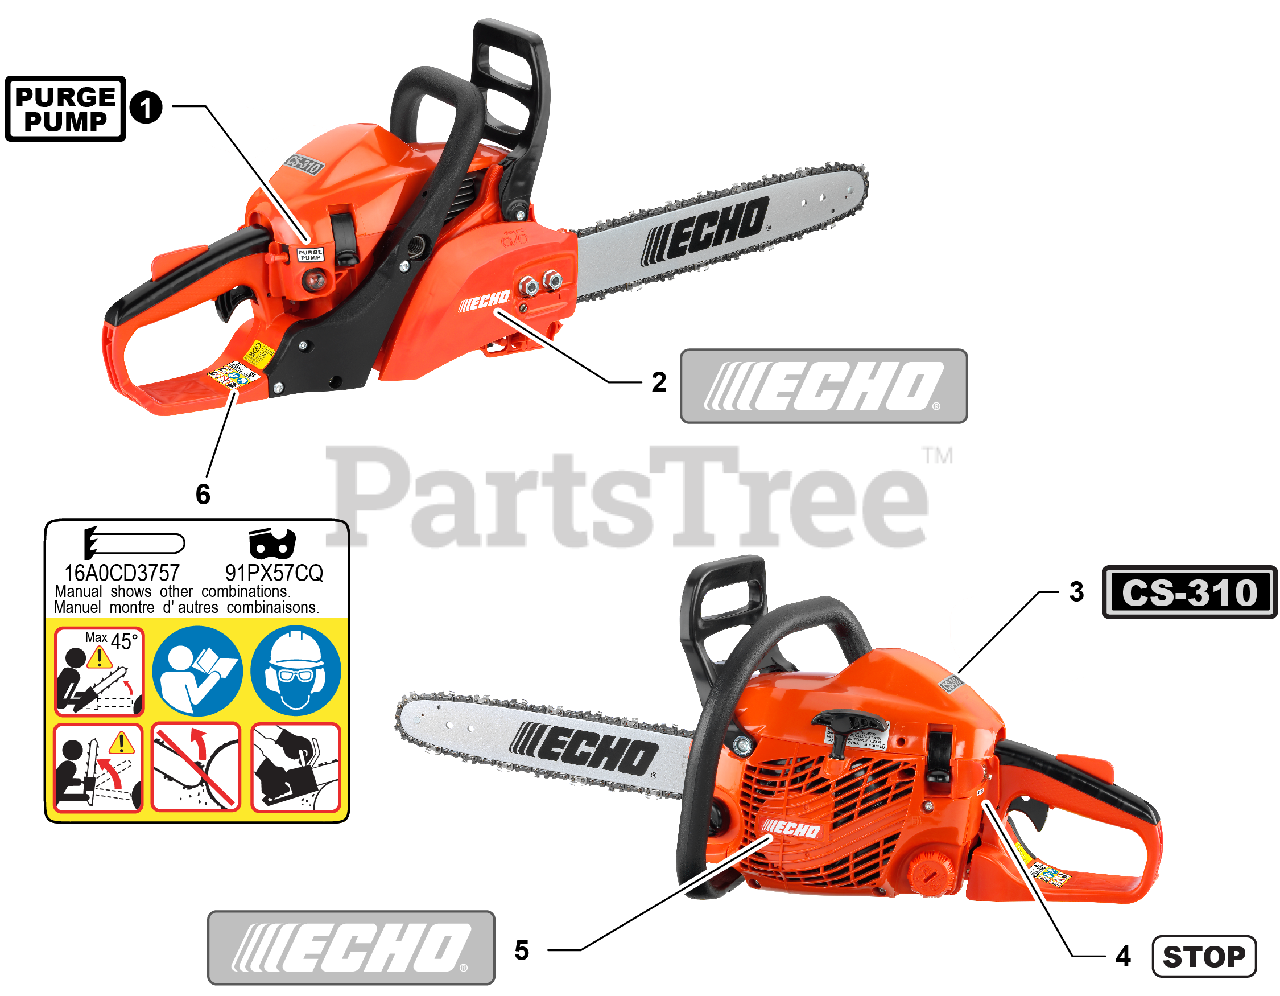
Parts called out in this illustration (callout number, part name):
1	LABEL, PURGE PUMP
2	LABEL, ECHO
3	LABEL, MODEL CS-310
4	LABEL, STOP
5	LABEL, ECHO
6	LABEL, CAUTION
